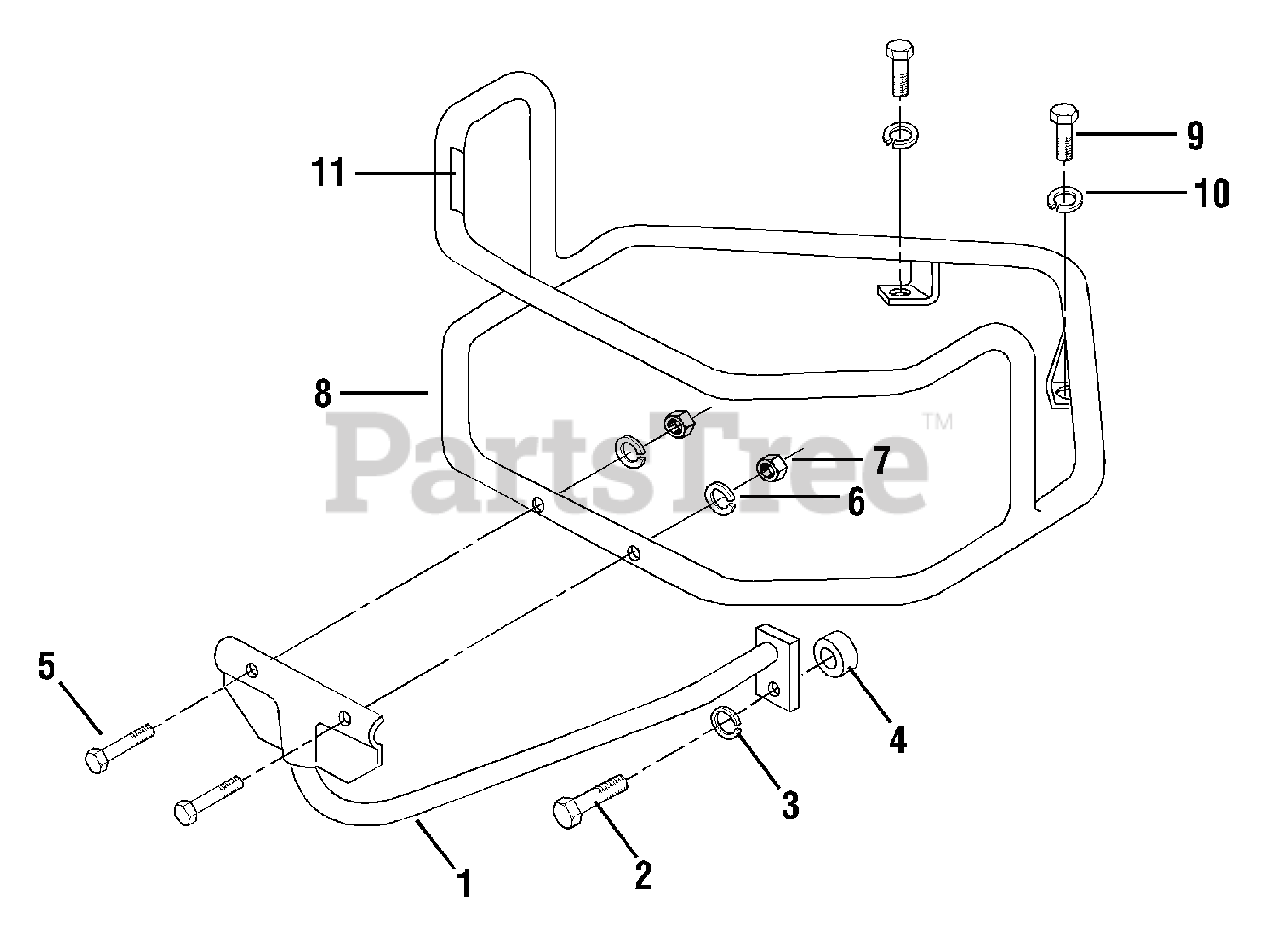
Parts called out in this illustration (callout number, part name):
1	Brace - bumper bottom
2	Bolt - hex hd., 1/2-13 x 1-1/2"
3	Lockwasher - spring lock, 1/2"
4	Spacer, 1/2"
5	Bolt - hex hd., 5/16-18 x 1-1/2"
6	Lockwasher - spring lock, 5/16"
7	Nut - hex, 5/16"-18
8	Bumper wraparound
9	Bolt - hex hd., 3/8-16 x 1"
10	Lockwasher - spring lock, 3/8"
11	Decal - for bumper
